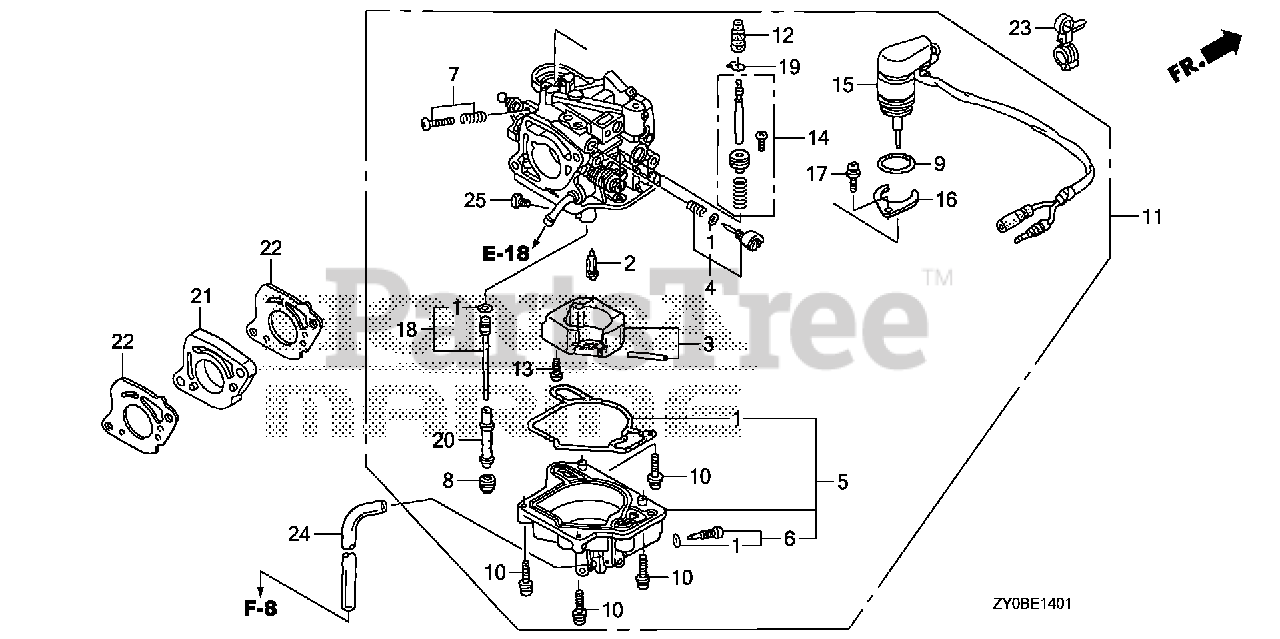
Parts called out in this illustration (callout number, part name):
1	GASKET SET
2	VALVE SET, FLOAT
5	CHAMBER SET, FLOAT
6	SCREW SET, DRAIN (CARBURETOR NO.)
7	SCREW SET
8	SCREW, PLUG
9	O-RING, BYSTARTER
10	SCREW-WASHER
11	CARBURETOR ASSY. (BJ08B A)
13	SCREW, PAN
14	PLUNGER SET, ACCELERATOR PUMP
15	BYSTARTER ASSY., AUTO
16	PLATE, SETTING
17	SCREW-WASHER
18	JET SET (#55)
19	CLIP, TUBE
20	NOZZLE, MAIN
21	INSULATOR, CARBURETOR
22	GASKET, CARBURETOR
23	CLIP, TUBE (135MM) (BLACK)
24	BULK HOSE, VINYL (4X7X8000) (95003-07(95003-07001-60M) (CARBURETOR NO.)
25	JET, MAIN (#120) (CARBURETOR NO.)
25	JET, MAIN (#122)
25	JET, MAIN (#125)
25	JET, MAIN (#128)
